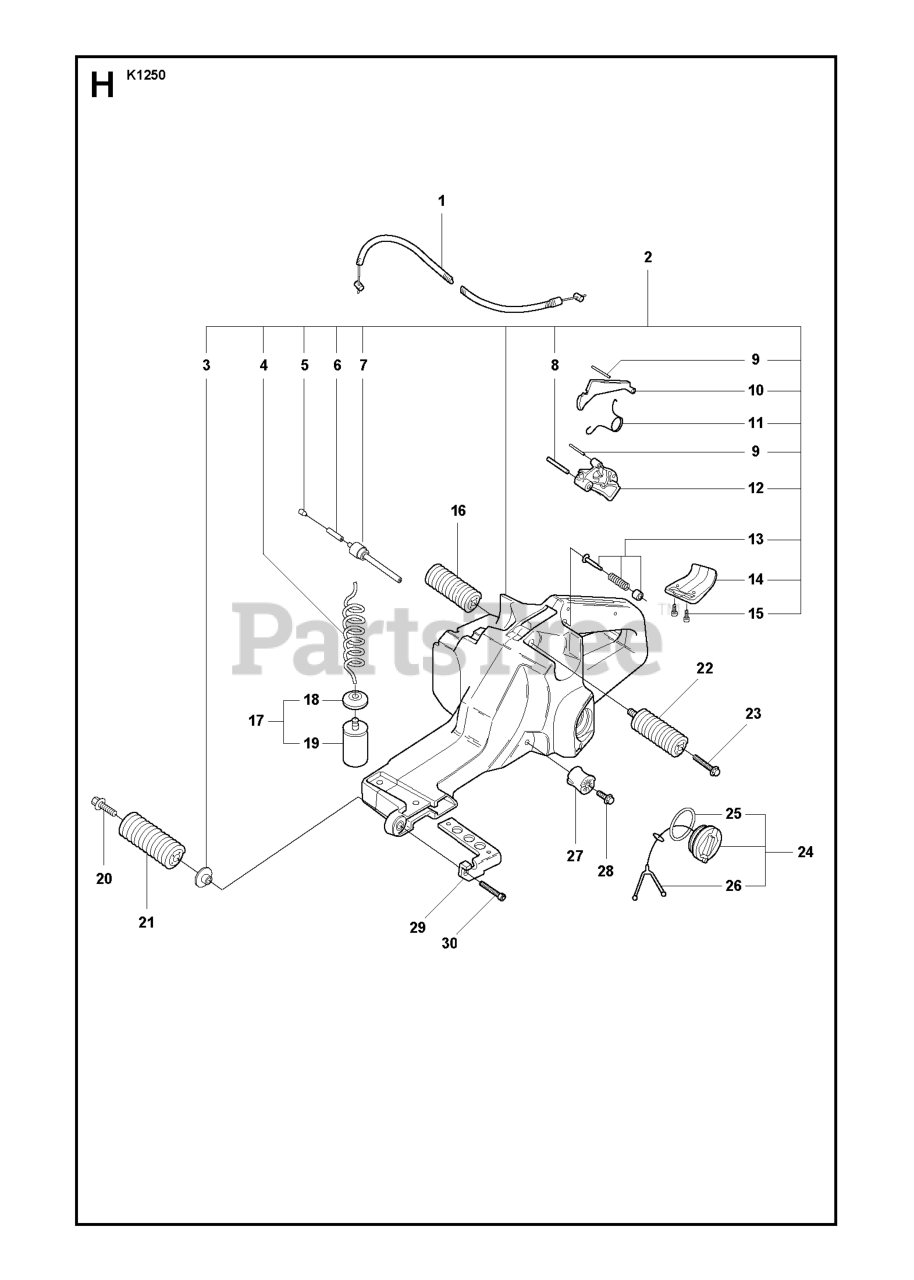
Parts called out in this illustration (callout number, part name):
1	THROTTLE WIRE
2	TANK COMP
4	HOSE
5	SINTER PLUG
6	FUEL HOSE
7	TANK VENT
8	PIN 4 X 35
9	PIN 3X25
10	THROTTLE CATCH
12	THROTTLE LEVER
13	THROTTLE CATCH,KIT
16	ANTIVIBE ELEMENT
21	ANTIVIBE ELEMENT
22	ANTIVIBE ELEMENT
23	SCREW MC6S 6X16
24	TANK CAP ASSY
27	ANTIVIBE ELEMENT
28	SCREW
